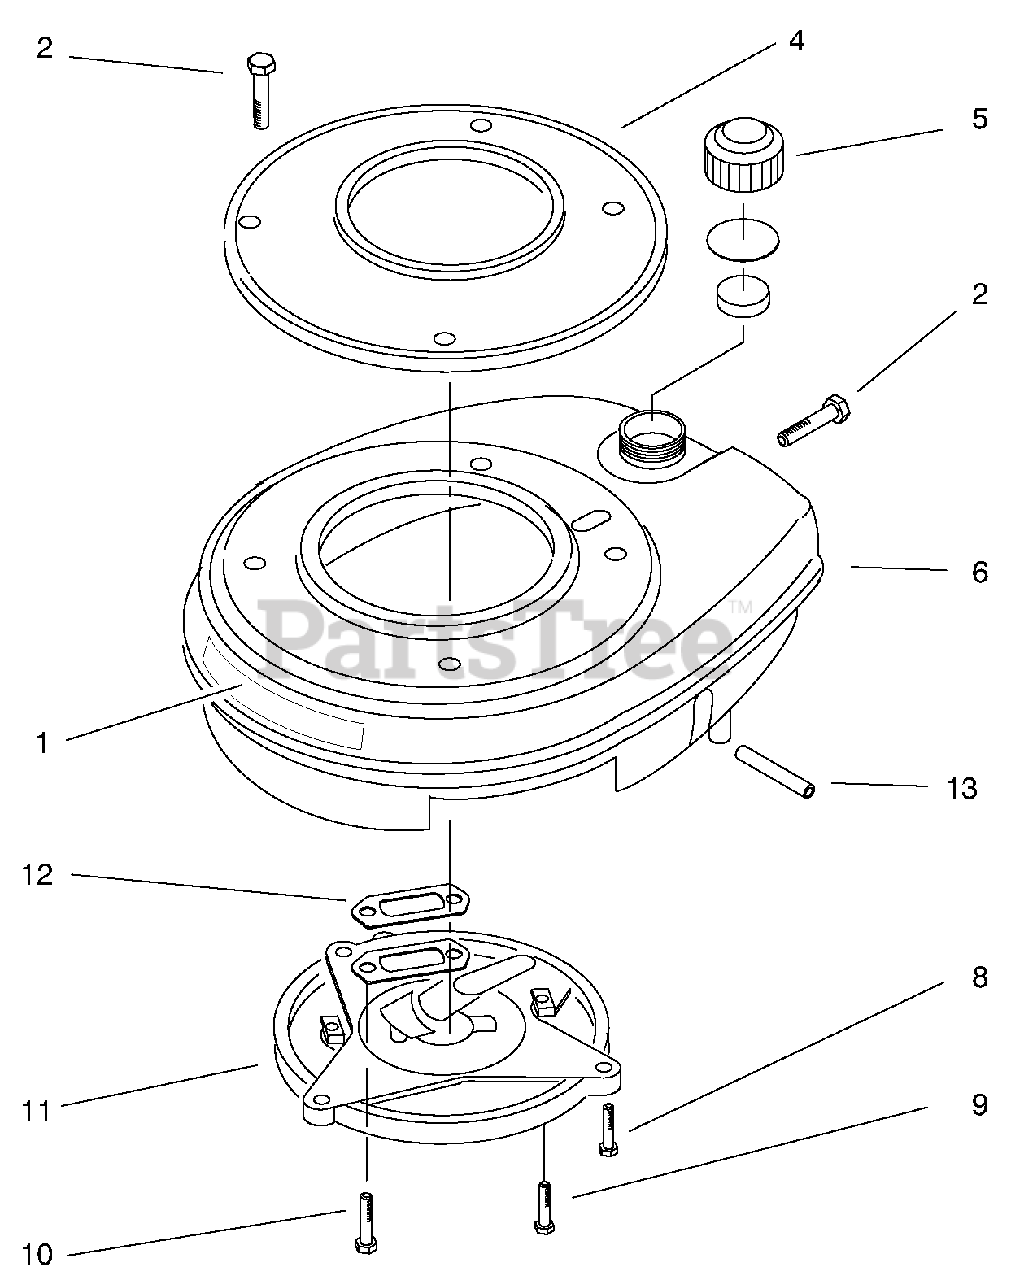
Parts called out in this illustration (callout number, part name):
1	Applique
4	Starter Base
5	Fuel Cap
6	Shroud-Engine
8	Screw-Muffler Pit. to Hsg.
9	Screw-Muffler Pit. to Block
11	Plate-Muffler
12	Gasket-Exhaust
13	Hose-Gas
